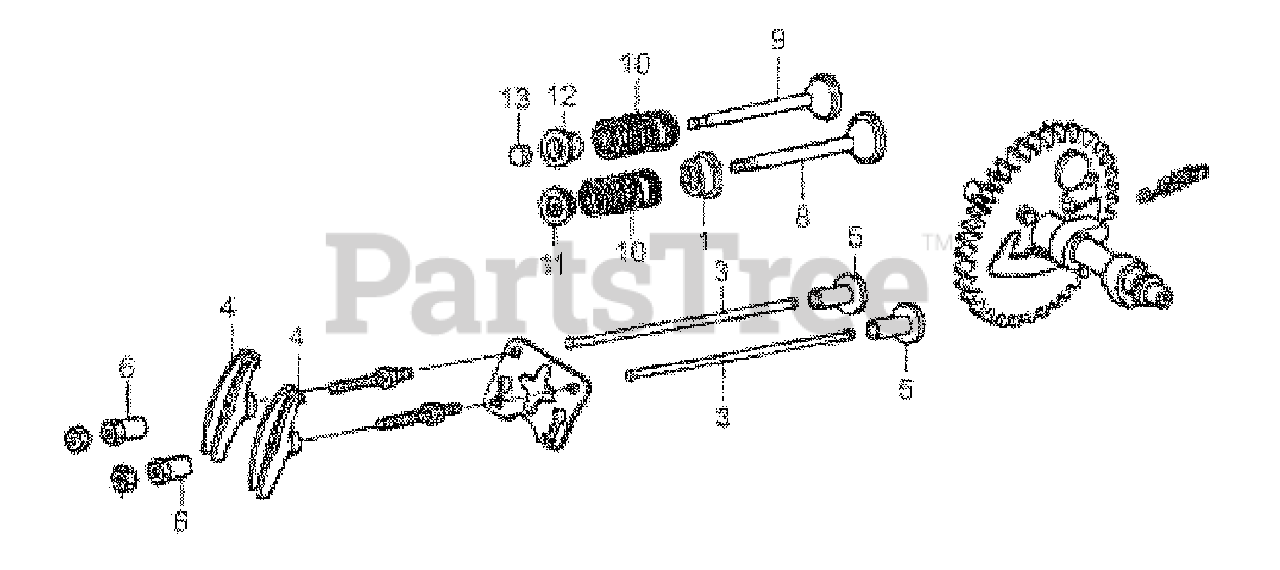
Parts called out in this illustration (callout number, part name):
1	SEAL, VALVE STEM
3	ROD, PUSH
4	ARM, ROCKER VALVE
5	LIFTER VALVE 8X35
6	NUT, PIVOT ADJUSTING
8	VALVE, INLET
9	VALVE, EXHAUST
10	SPRING, VALVE
11	RETAINER, INLET VALVE SPRG
12	RETAINER, EXH VALVE SPRG
13	ROTATOR, CAP
